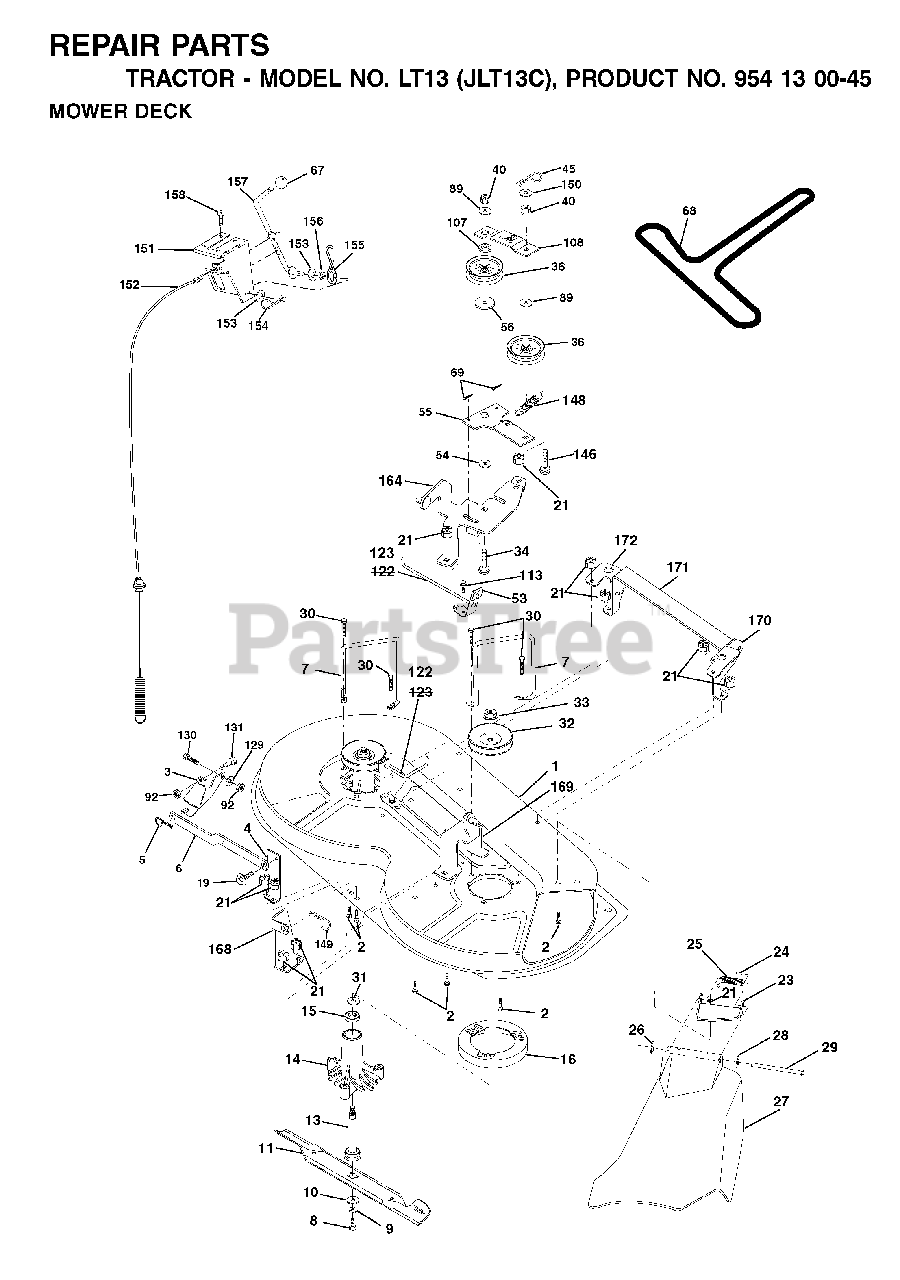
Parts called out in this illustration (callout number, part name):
2	BOLT
3	BRKT ASM SWAY BAR
5	RETAINER-SPRNG RB
6	REAR SUSP ARM
7	KEEPER LH
8	BLADE BOLT
9	LOCKWASHER
10	WASHER.BLADE
11	BLADE, HI-LIFT 36" PREMIUM
13	SHAFT ASM VENT
14	HSG MANDREL
16	STRIPPER, MWR ROUND
19	BOLT SHD 5/16-18
21	LOCKNUT
23	BRACKET ASM DEFLECTOR
24	CAP-SLEEVE LT
25	SPRING TORSION
26	NUT PUSH M
28	WASHER
29	HINGE ROD
30	SCREW THDROL ROLLING WASHER HD
31	WASHER
32	PULLEY, MANDREL
33	NUT, FLG TOPLOCK 9/16"
34	BOLT
36	FLAT IDLER PULLEY
40	LOCKNUT
45	RETAINER M
53	BRAKE ASSEMBLY
54	HARDENED WASHER
55	IDLER ARM
56	SPACER.RETAINER.MOWER
67	KNOB T (3/8 HOLE)
69	COTTER PIN
89	WASHER GT
92	NUT
107	SPACER.IDLER.ARM
108	STIFFENER.IDLER.ARM
129	WASHER
131	BOLT D
146	BOLT, CARRIAGE IDLER
148	IDLER RETURN SPRING
149	SPRING.RETAINER.YELLOW.ZINC
150	WASHER PM
151	BRACKET, CLUTCH CABLE
153	WASHER FLAT 3/8"
154	SPRING RETAINER
155	SPRING RETENTION LEVER
156	SPACER CLUTCH CABLE
157	ROD CLUTCH CABLE 3/8"
158	SCREW LT
171	BRACE
